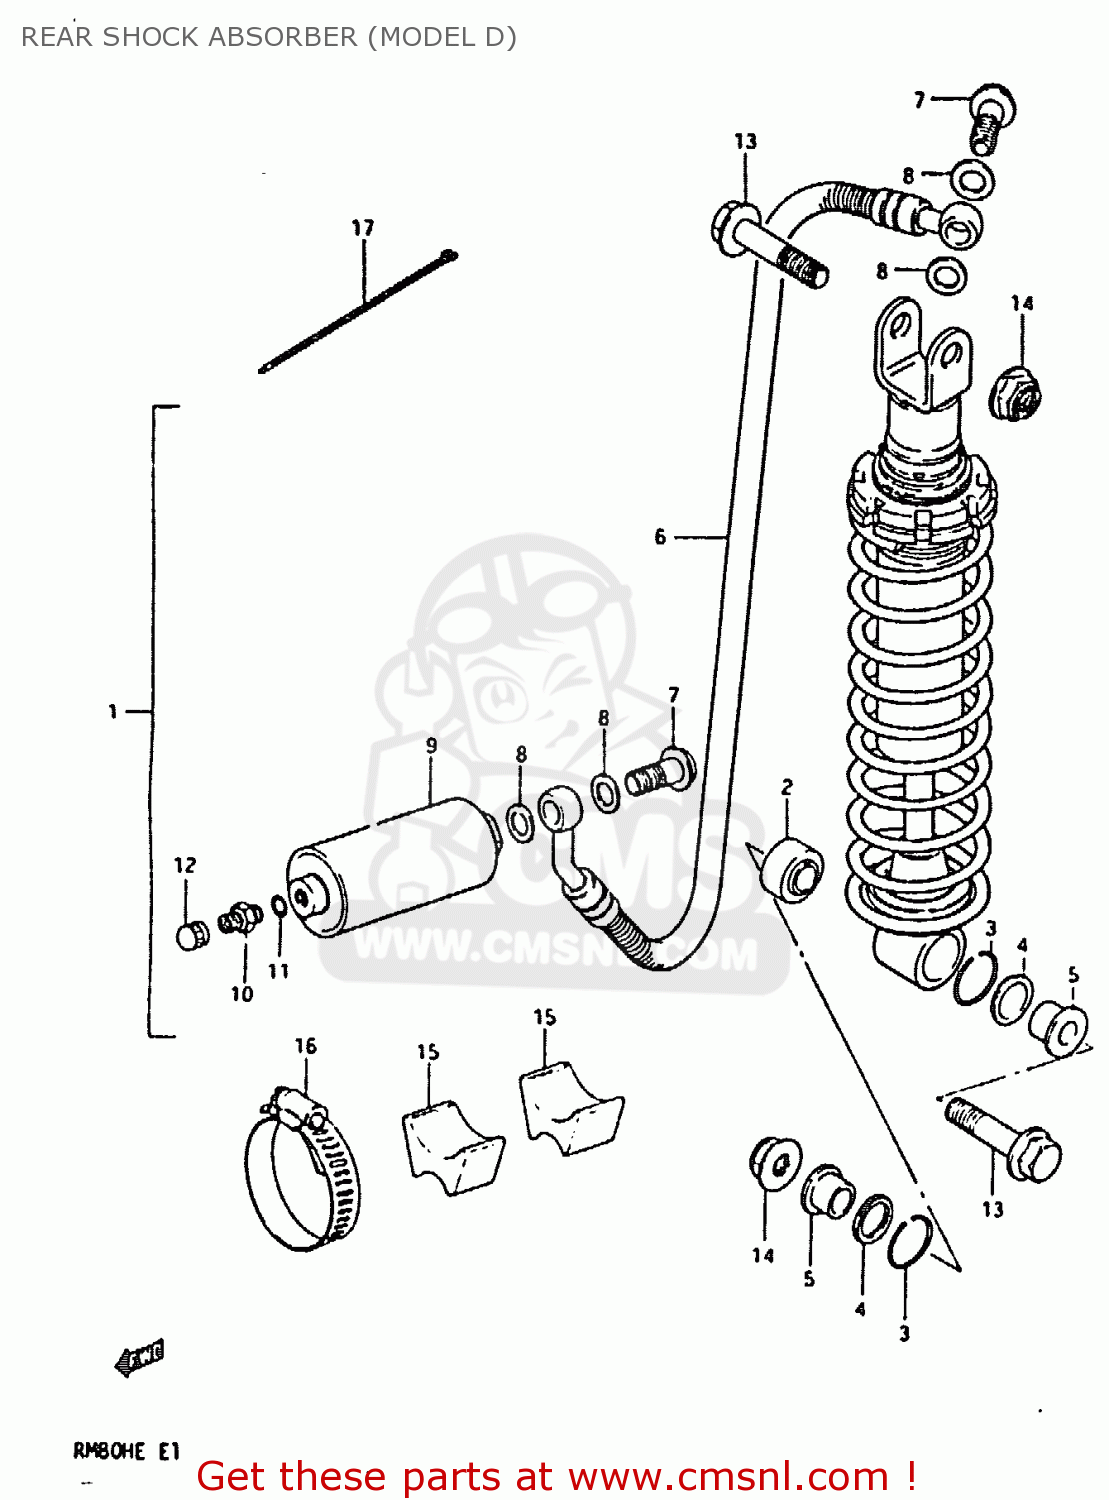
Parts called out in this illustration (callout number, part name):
1	SHOCK ABSORBER, REAR
2	BEARING
3	RING
4	DUST SEAL
5	SPACER
6	HOSE,REAR SHOCK ABSORBER
7	BOLT,REAR SHOCK ABSORBER
8	WASHER
9	RESERVE TANK,REAR SHOCK
10	VALVE,FRONT FORK AIR
11	O-RING (D:3.8 ID:19)
12	CAP,FRONT FORK AIR VALVE
13	BOLT(10X50)
14	NUT
15	CUSHION,REAR SHOCK ABSORBER
16	CLAMP
17	CLAMP
